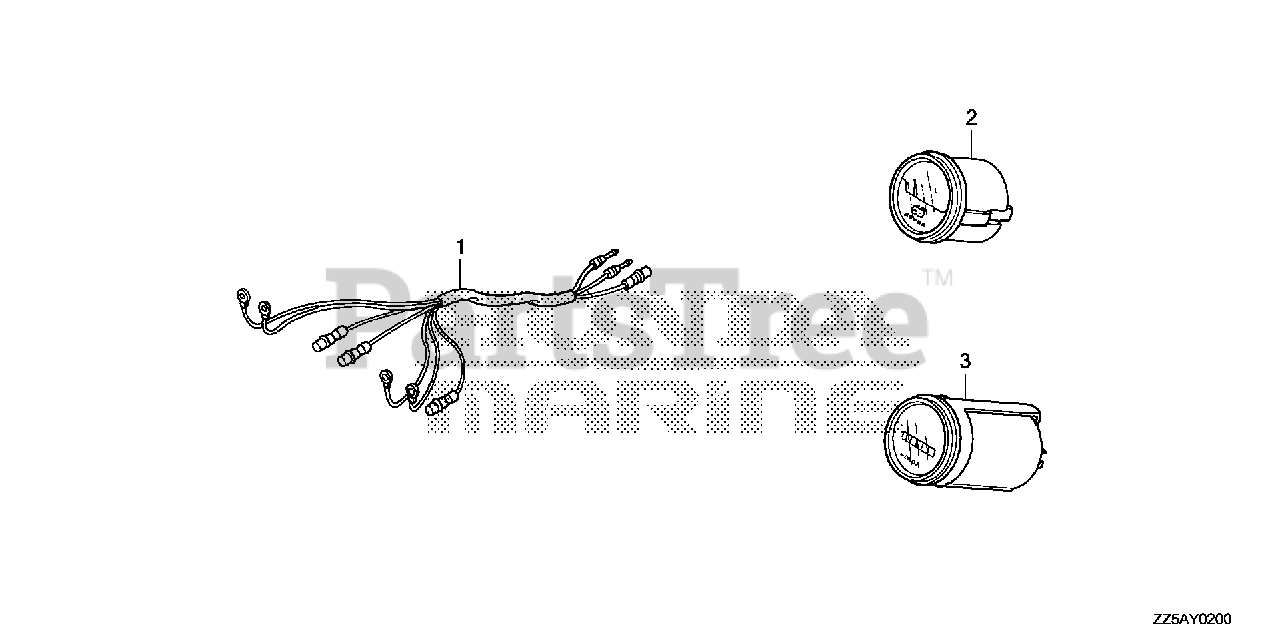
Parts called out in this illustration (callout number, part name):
1	HARNESS ASSY., METER (B)
2	METER ASSY., VOLT (NOT AVAILABLE)
3	METER ASSY., HOUR L.C.D.
